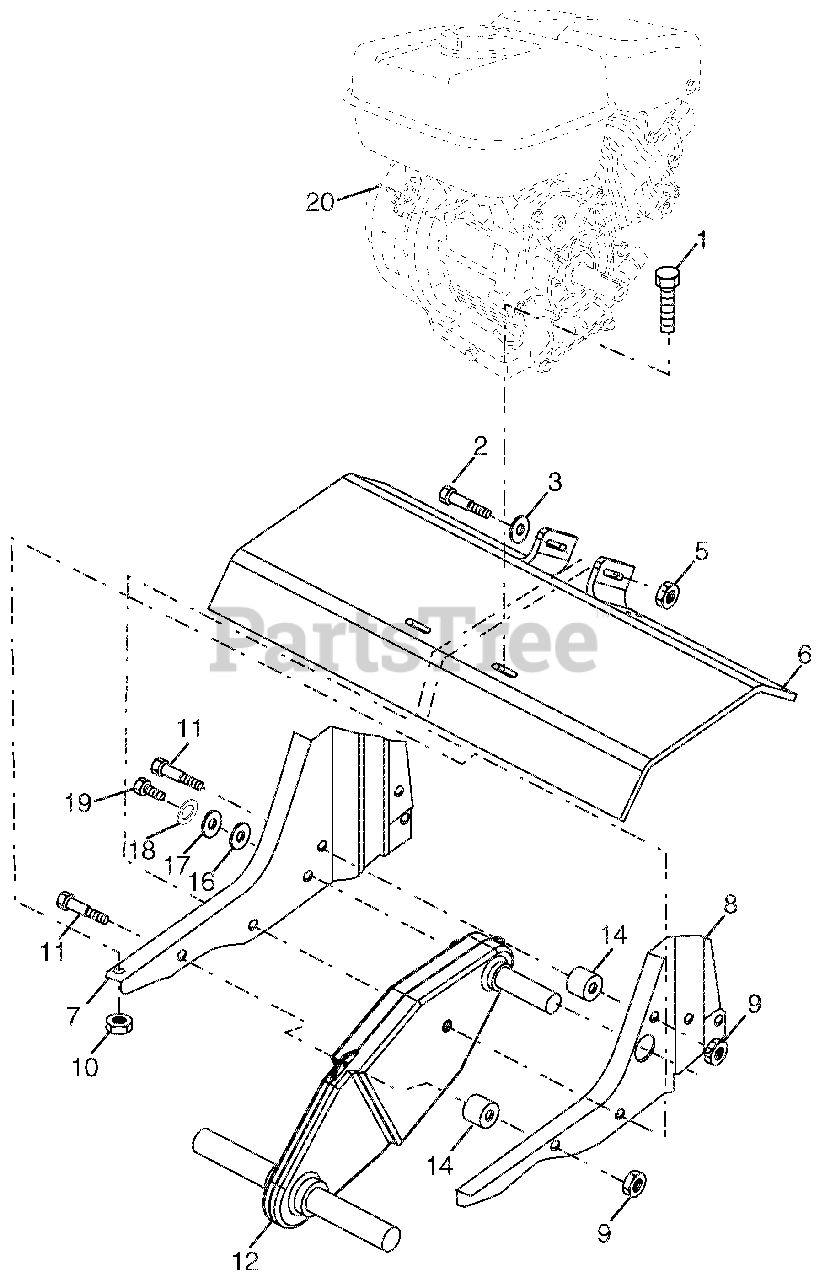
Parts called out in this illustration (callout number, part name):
1	Bolt, Hex Head, Gr. 25/16-18 x
2	Bolt, Hex Head, 3/8-16 x 3-1/4
3	Washer 13/32 x 13/16 x 11 Ga.
5	Nut, Hex, Flangelock 3/8-16
6	SHIELD, TINE
7	Bracket, Engine, R.H.
8	Bracket, Engine, L.H.
9	Nut, Hex
10	Nut, Hex, Flangelock
11	Bolt, Shoulder
12	Transmission
14	SPLIT SPACER
16	Washer, 9/32 x 7/8 x 12 Ga.
17	Washer, 9/32 x 1-1/4 x 16 Ga.
18	Washer, Lock 1/4
19	Bolt, Hex Head, Gr. 51/4-28 x
20	Engine, Subaru, Model Number EX170DT1031 (For engine service and replacement parts,
